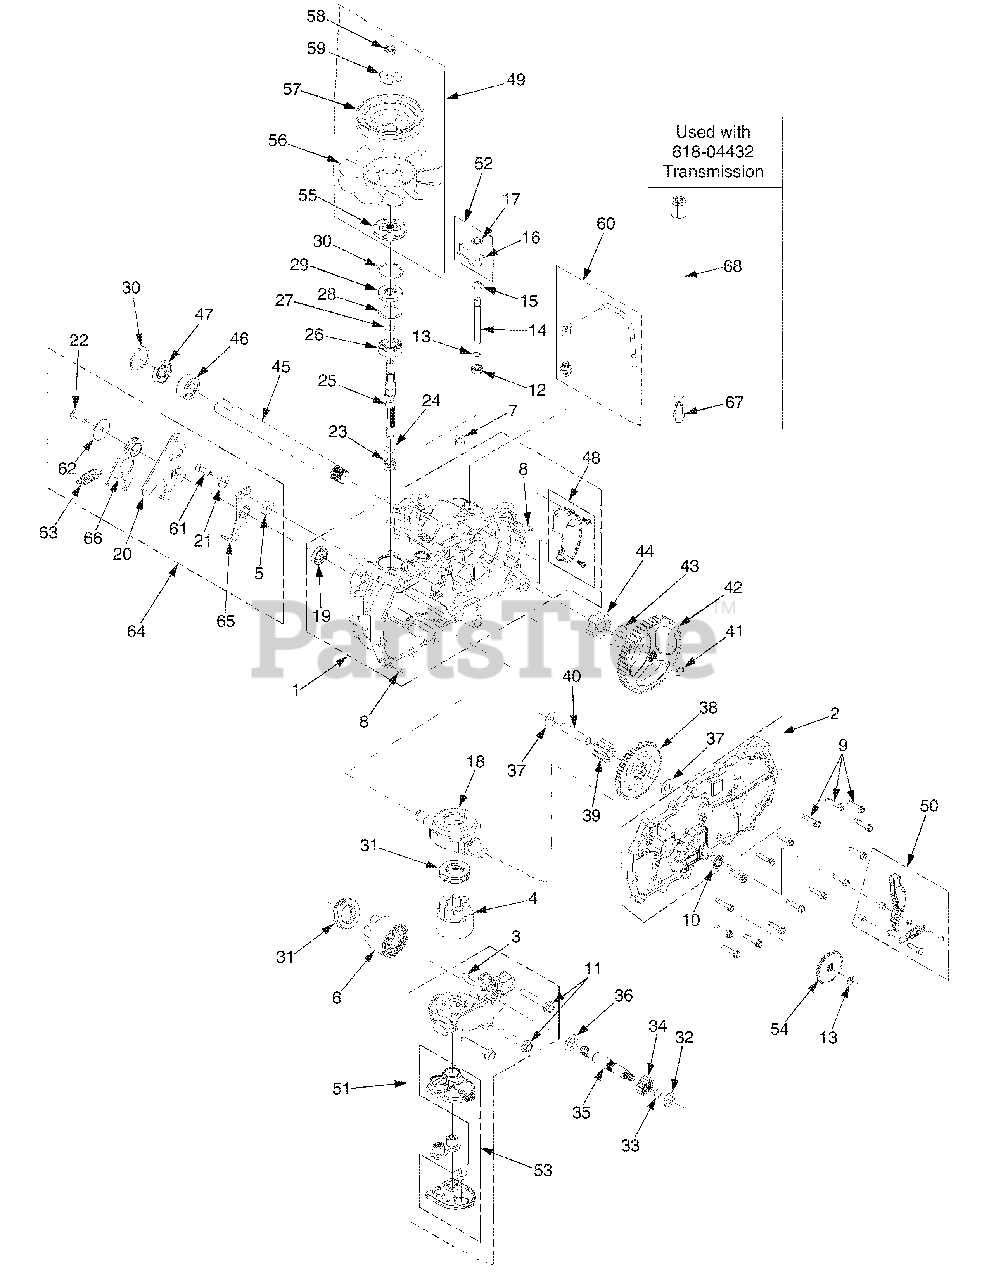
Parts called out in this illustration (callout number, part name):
1	Housing Assembly, Main RH
2	Side Assembly, RH
3	Plate, Bypass
4	Pump Block Assembly
5	Spacer, .32 x 1.005
6	Motor Block Assembly
8	Pin, Stainless
9	Screw, Hex Self Tapping, 1/4-20 x 1.25
10	Seal, Brake
11	Bolt, Hex Flange, 3/8-24 x 2.5
12	Seal, Lip, .375 x .75 x .25
13	Ring, Retaining, .375 Ext.
14	Rod, Bypass
15	Ring, Retaining, .75 Int.
16	Arm, Bypass
17	Ring, Retaining, .375 Push
18	Swashplate, Trunnion
19	Seal, Lip, 18 x 32 x 7
20	Arm, Control RH
21	Washer, Flat, 11/32 x 7/8 x 1/16
22	Screw, 5/16-24 x 1.0
23	Spring, Compression
24	Washer, .591 x .787 x .04
25	Shaft, Input
26	Bearing, Ball, 17mm x 40 x 12
27	Ring, Wire Retaining, .561
29	Seal, Lip, 17 x 40 x 7
30	Ring, Retaining
31	Bearing, Thrust, 30 x 52 x 13
32	Washer, Flat, 5/8 x 1.0 x .05
33	Ring, Retaining
34	Gear, Pinion, 13T
35	Shaft, Motor
36	Washer, .71 x 1.16 x .04
37	Washer, HT, .5 x 1.0 x .032
38	Gear, 10T/48T
39	Gear, Jackshaft, 10T
40	Pin, Jackshaft
41	Ring, Spiral Retaining
42	Gear, Bull, 52T
43	Washer, 1.018 x 1.571 x .105
44	Bearing, Sleeve
45	Shaft, Axle, 1.0 x 11.7
46	Bushing, Axle
47	Seal, Lip, 1.0 x 1.57 x .25
48	Kit, Expansion Plate, RH
49	Kit, Fan-Pulley
50	Kit, Brake Arm
51	Kit, Center Section-Filter RH
52	Kit, Bypass Arm
53	Kit, Filter
54	Disc, Brake Cog
55	Hub, Pulley
56	Fan, 7" 10 Blade
57	Pulley, 4.5
58	Nut, Hex Insert Lock, 1/2-20
59	Washer, OD Slotted
60	Kit, Breather
61	Screw, Hx Patch, 5/16-24 x 1.0
62	Washer, 1.5 x .34 x .062
63	Spring, Extension
64	Kit, Return Assembly RH
65	Arm, Neutral RH
66	Assemble, Return, Bi-Direct.
67	Fitting, w/Cap
68	Hose Assembly
